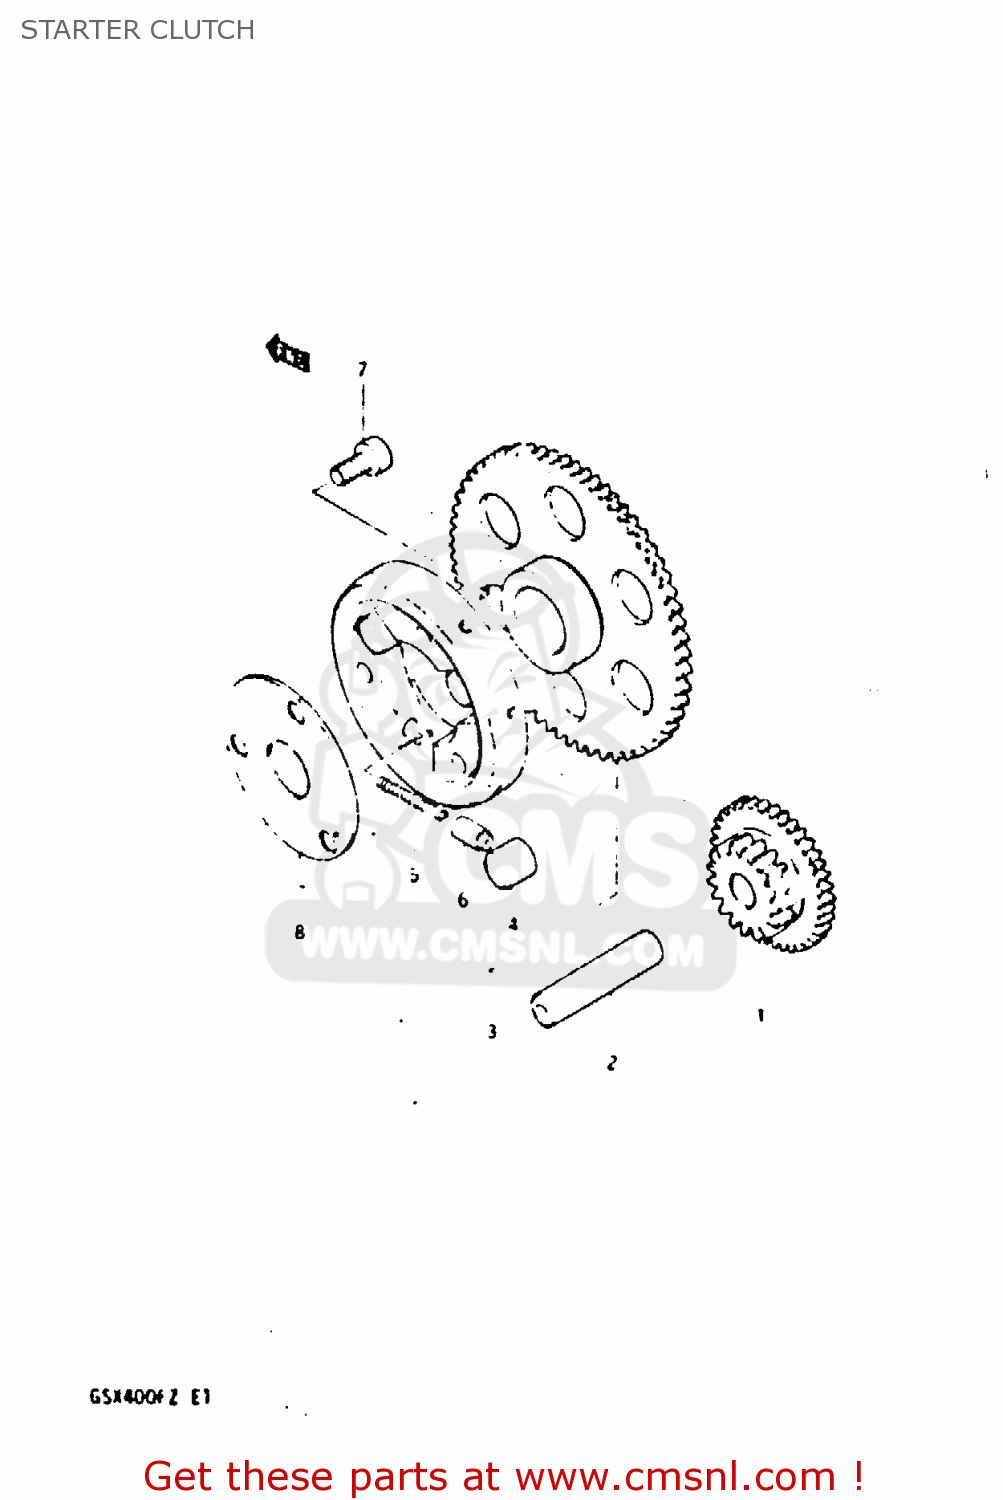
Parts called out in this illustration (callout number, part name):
1	GEAR, STARTER IDLE (NT:47/18)
2	PIN(7.4X13X40)
3	STARTER CLUTCH SET
4	ROLLER(15X13)
5	SPRING
6	PIECE,PUSH
7	BOLT
8	SHIM,STARTER CLUTCH HUB
